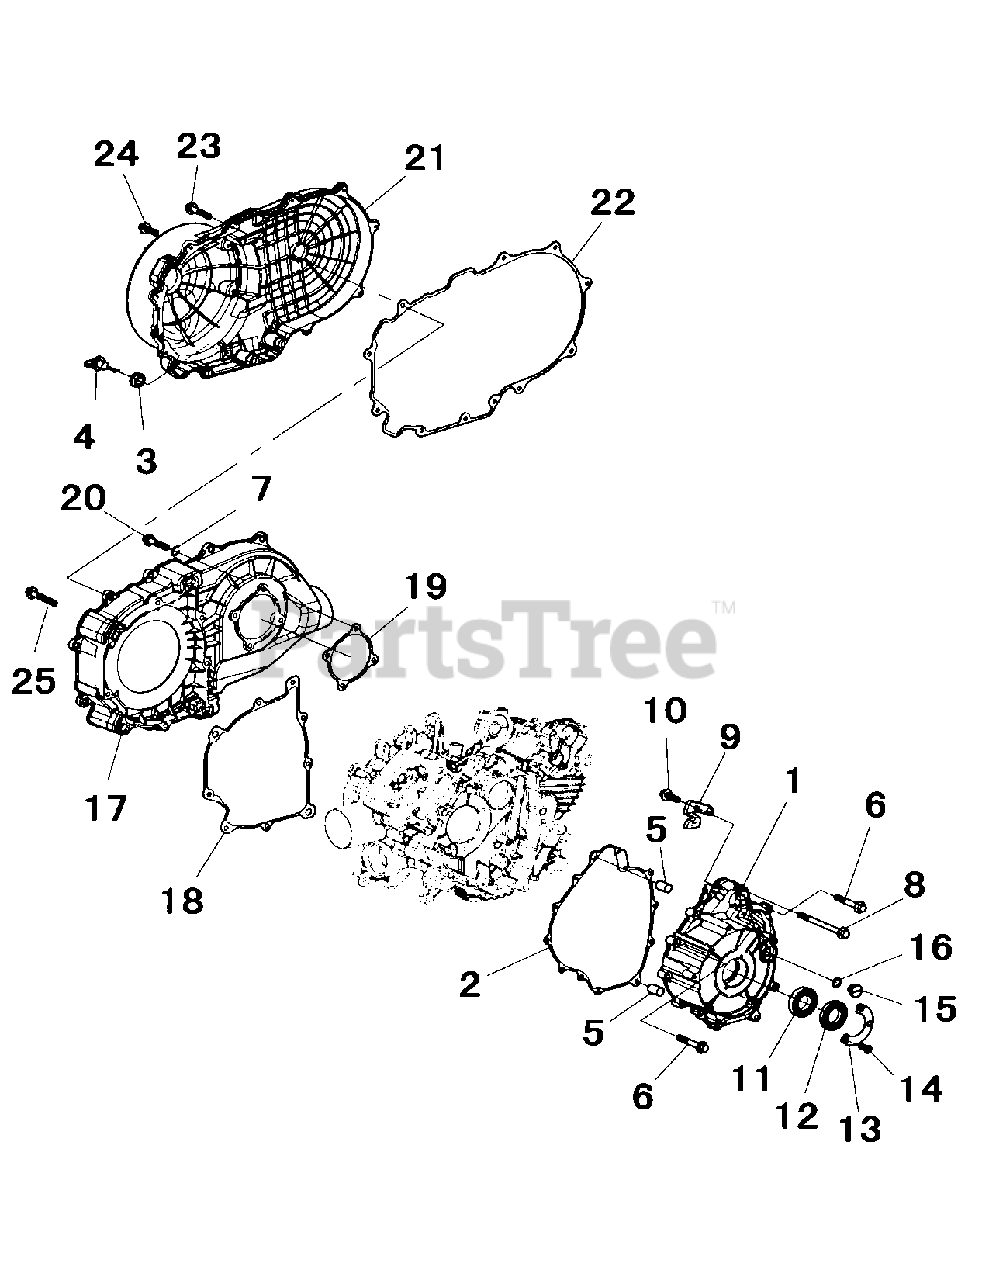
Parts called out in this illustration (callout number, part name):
1	Cover-Left
2	Gasket-Left Front
3	Rubber Sheath
4	Piled Head Clutch
6	Flangebolt M6X30
8	Flangebolt M6X40
9	Press Wire Plate -
10	Flangebolt M6X12
12	Oil Seal
13	Pressure Plate-Lef
15	Hand Hole Cover
16	O-Ring 13.4X2.35
17	Seat Cover-Compl C
18	Gasket-Clutch Cove
19	Gasket-Clutch Cove
20	Flange Bolt M6X32
21	Clutch Cover Compl
22	Gasket-Clutch Cove
23	Flange Bolt M6X25
24	Flangebolt M6X16
25	Flange Bolt M6X50
